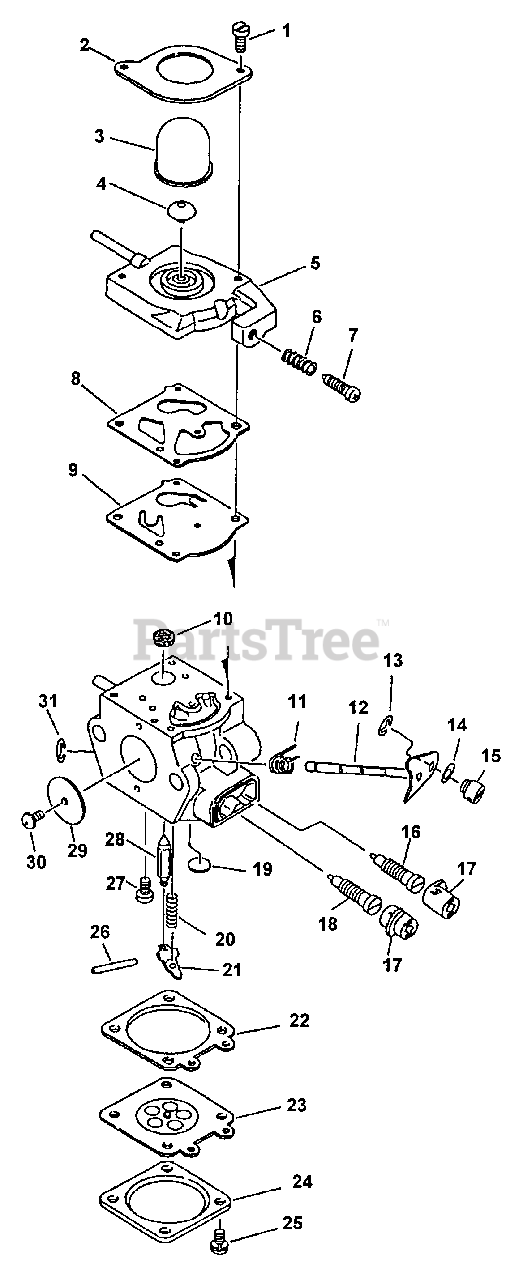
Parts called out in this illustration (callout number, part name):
2	RETAINER, PURGE BULB
3	BULB, PURGE
4	VALVE, CHECK
5	COVER, FUEL PUMP
6	SPRING, IDLE ADJUST
7	SCREW, IDLE ADJUST
8	GASKET, PUMP
9	DIAPHRAGM, PUMP
10	STRAINER
11	SPRING, THROTTLE RETURN
12	SHAFT, THROTTLE
16	NEEDLE, HIGH SPEED
17	CAP, LIMITER
18	NEEDLE, IDLE
19	PLUG, WELCH
20	SPRING, METERING LEVER
21	LEVER, METERING
22	GASKET, DIAPHRAGM
23	DIAPHRAGM, METERING
24	COVER, METERING DIAPHRAGM
25	SCREW
26	PIN, METERING LEVER
27	SCREW, METERING LEVER PIN
28	VALVE, INLET NEEDLE
29	VALVE, THROTTLE
